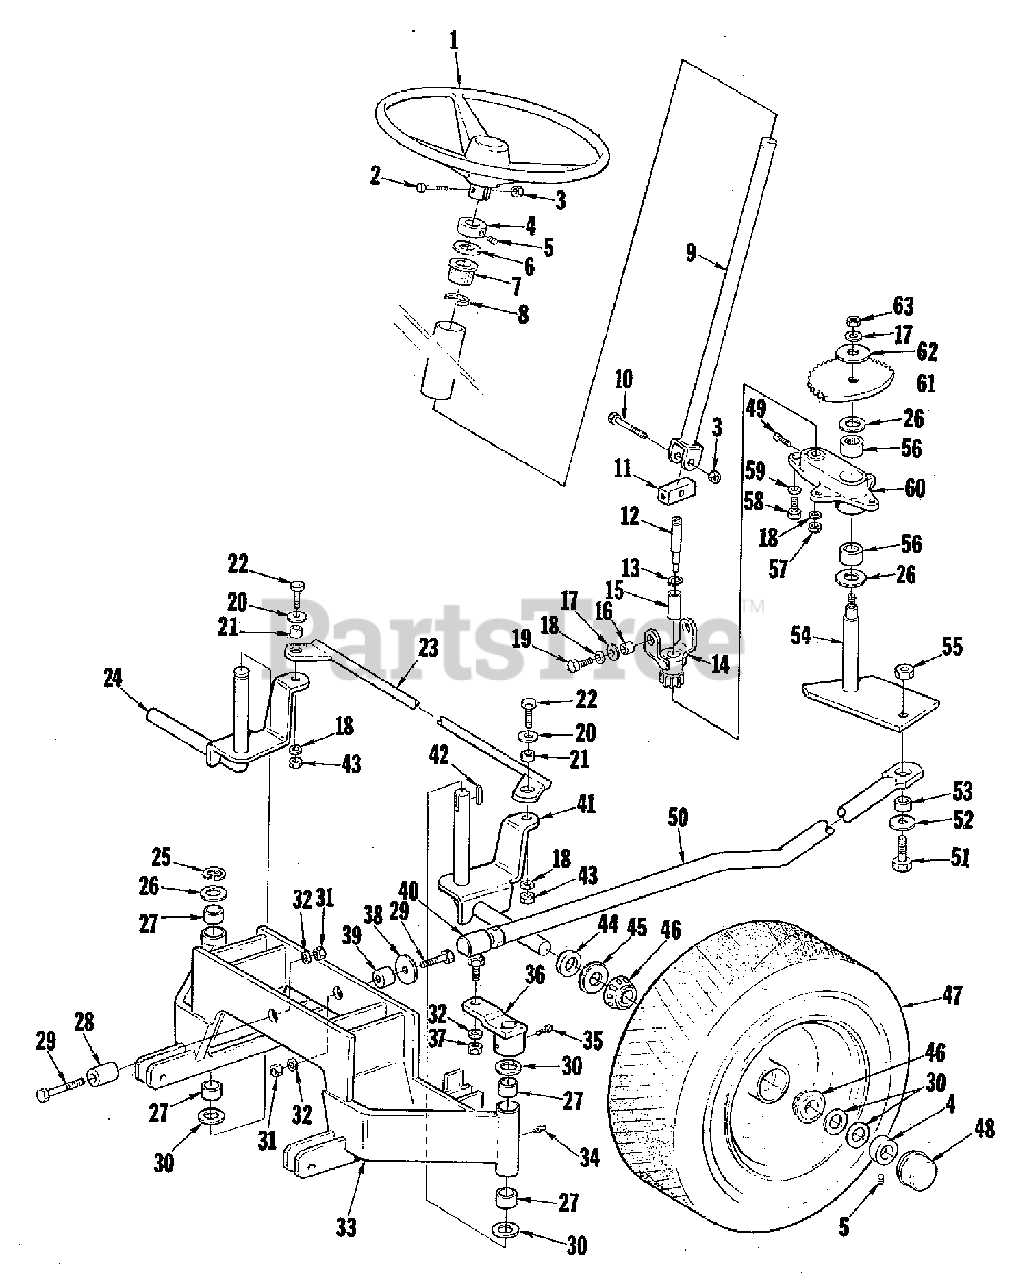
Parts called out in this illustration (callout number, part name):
1	WHEEL, Steering
2	SCREW, Hex Head Cap, 5/16-18 x 1-1/4
3	NUT, Hex Lock, 5/16-18
5	SETSCREW, 5/16-18 x 1/4
6	WASHER, Special
7	BUSHING, Steering
9	SHAFT ASSEMBLY, Steering
10	SCREW, Hex Head Cap, 5/16-18 x 1-1/2
11	PIN, Universal Joint
12	PIN, Eccentric
13	RING, Retainer
14	BUSHING ASSEMBLY
17	WASHER, Flat, 3/8
18	WASHER, Lock, 3/8
19	SCREW, Hex Head Cap, 3/8-16 x 3/4
20	WASHER, Flat, 3/8
22	SCREW, Cap, 3/8-16 x 1-1/4
23	ROD, Tie Assembly
24	SPINDLE ASSEMBLY, R.H.
25	RING, Retaining
29	SCREW, Hex Head Cap, 1/2-13 x 2
31	NUT, Hex Fin
32	WASHER, Lock, 1/2
33	AXLE ASSEMBLY, Front
34	FITTING, Lube, Straight
35	SETSCREW, Square Head, 5/16-18 x 1/2
36	ARM ASSEMBLY, Steering
37	NUT, Hex Jam, 1/2-20
38	WASHER, Flat
41	SPINDLE ASSEMBLY, L.H.
43	NUT, Hex Fin
46	CONE, Bearing
47	WHEEL & TIRE ASSEMBLY, Front
51	SCREW, Hex Head Cap, 1/2-13 x 1-1/4
54	ARM ASSEMBLY, Steering
55	NUT, Hex Lock, 1/2-13
56	NEEDLE BEARING
57	NUT, Hex Lock, 3/8-16
58	SCREW, Hex Head Cap, 5/16-18 x 5/8
59	WASHER, Lock, 5/16
60	BRACKET, Steering
61	GEAR, Steering
62	WASHER, Arbor
63	NUT, Hex Lock, 7/16
